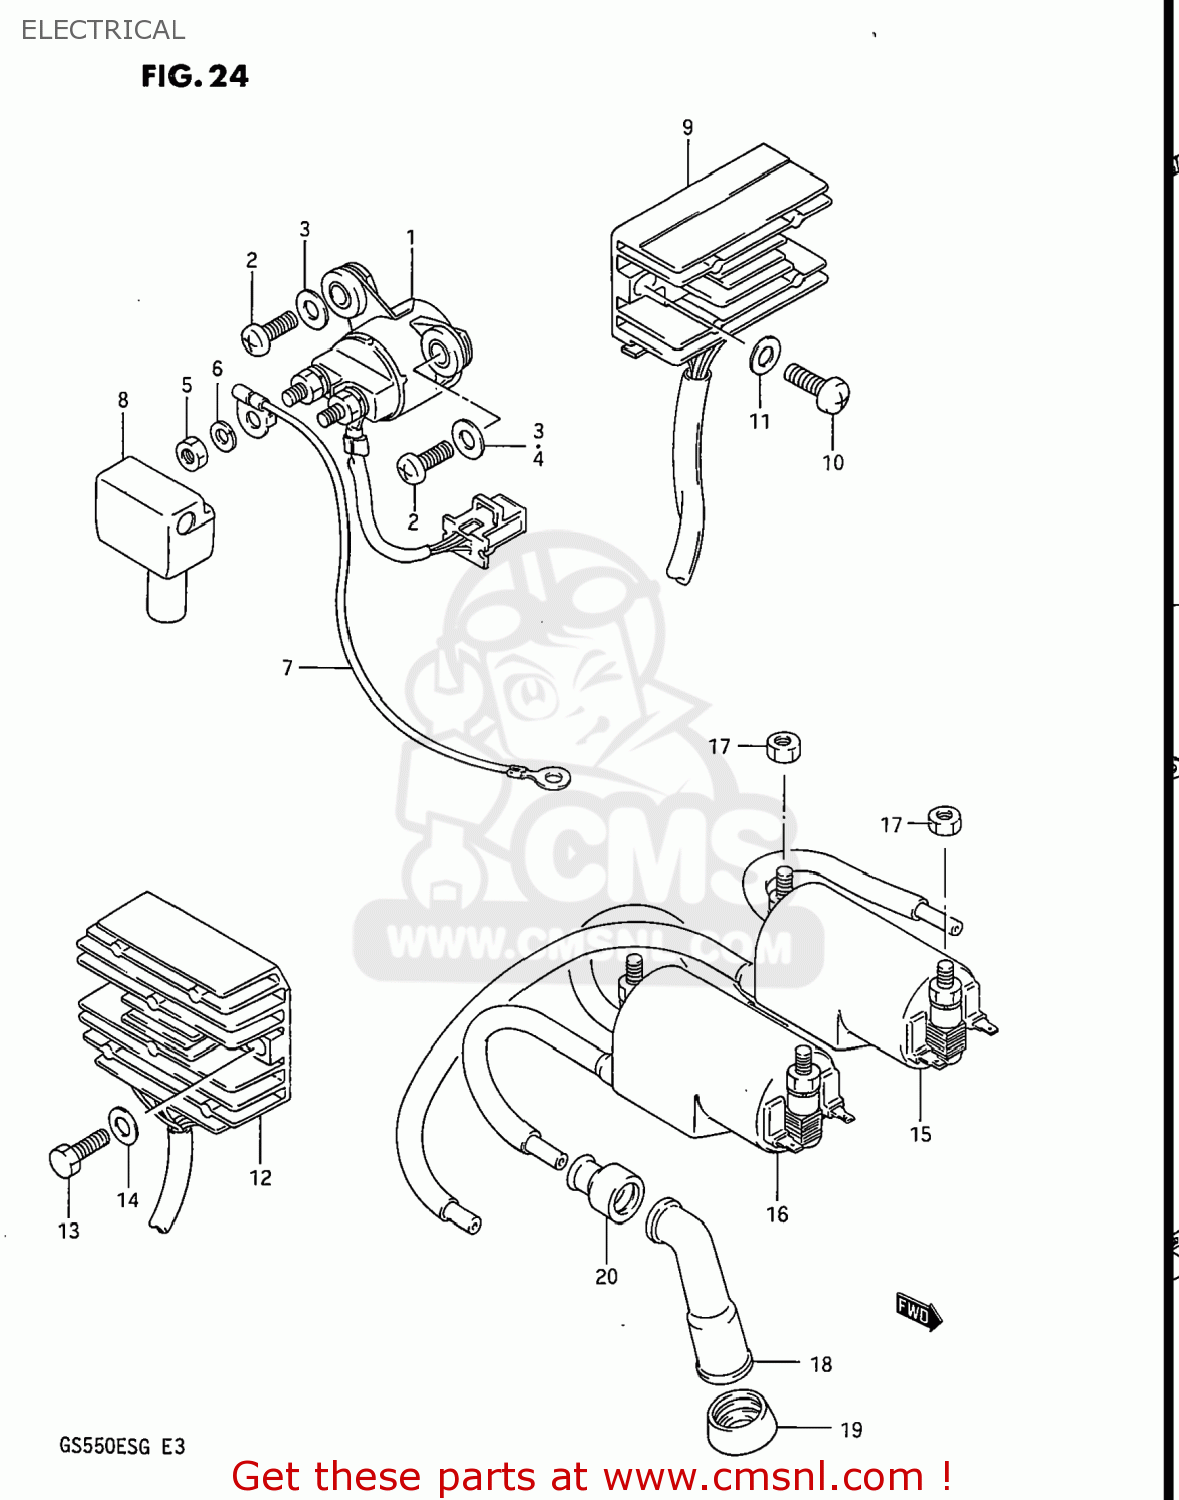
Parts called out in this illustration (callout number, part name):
1	RELAY,STARTER SWITCH
2	SCREW
3	WASHER
4	WASHER
5	NUT
6	WASHER,LOCK
7	WIRE,STARTER MOTOR LEAD
8	CAP,STARTER RELAY TERMINAL
9	RECTIFIER ASSEMBLY
10	SCREW
11	WASHER
12	RECTIFIER ASSEMBLY
13	SCREW(6X20)
14	WASHER
15	COIL ASSEMBLY,IGNITION
16	COIL ASSEMBLY,IGNITION
17	NUT
18	CAP ASSY,SPARK PLUG
19	SEAL,SPARK PLUG CAP
20	SEAL,SPARK PLU
